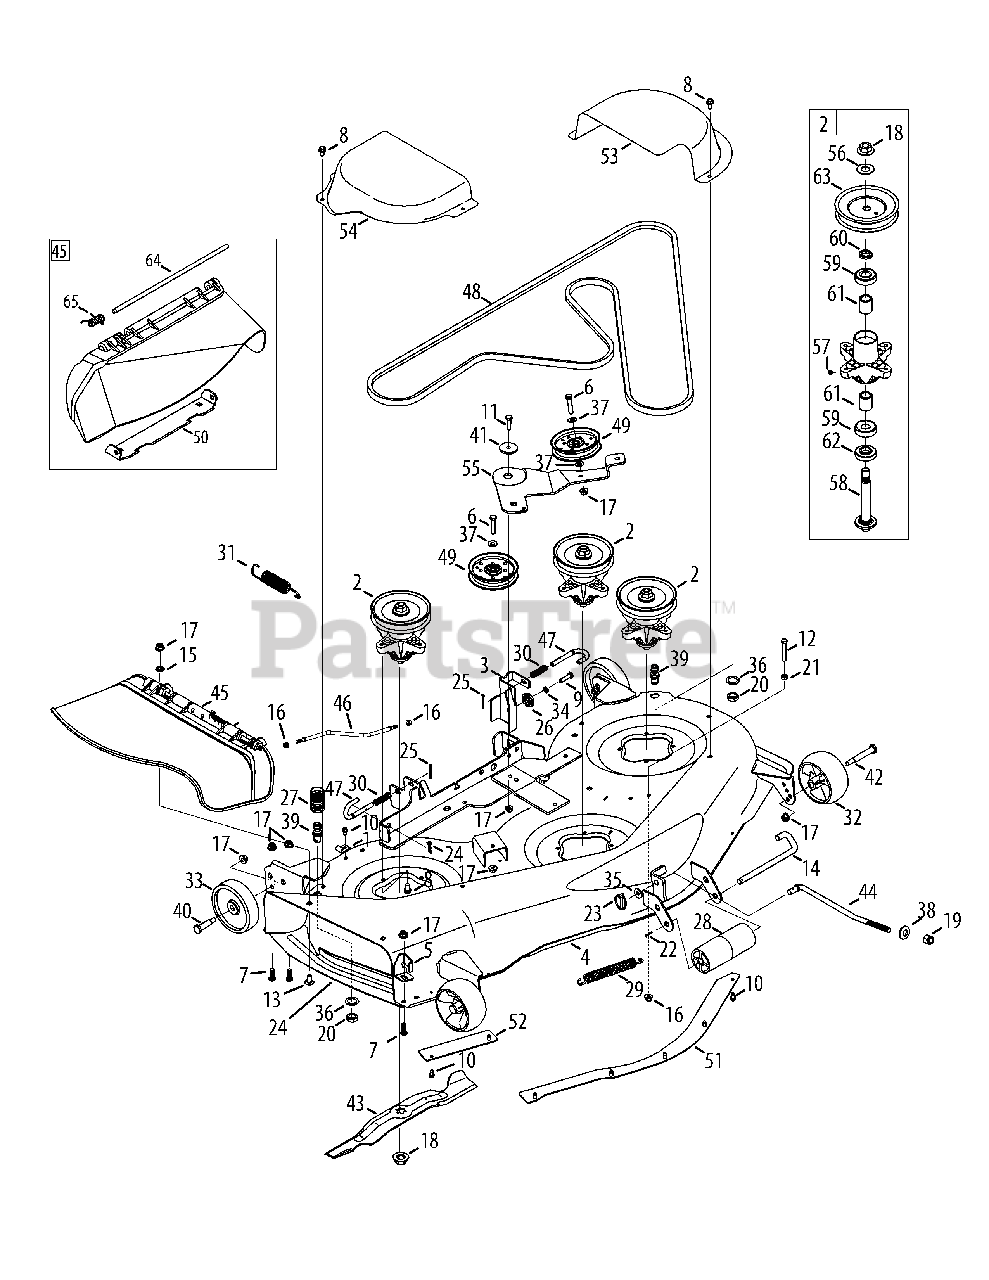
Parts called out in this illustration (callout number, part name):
1	Hook Retainer Bracket
2	Pulley Spindle Assembly, 5.39
3	Deck Hanger Bracket Assembly
6	Hex Screw, 3/8-16x1.75
7	Hex Screw, 3/8-16x1.00
8	Taptite Screw, 5/16-18x.750
9	Hex Screw, 5/16-18x1.25
10	Taptite Screw, 1/4-20x0.500
11	Hex Screw, 3/8-16x1.25
12	Hex Screw, 5/16-18x2.0
13	Carriage Bolt, 3/8-16x0.75
14	Roller Pin, 1/2 DIA x 7.31 LG
15	Push Nut, 3/8
16	Flangelock Nut, 5/16-18
17	Flangelock Nut, 3/8-16
18	Flange Nut, 5/8-18
19	Flexlock Nut, 1/2-13
20	Hex Nut, M16-1.5 DIN 936
21	Hex Nut, 5/16-18:GR5
22	Cotter Pin, 3/32x1.0
23	Lynch Pin, .1875
24	Finger Guard
25	Cotter Pin, 1/8 x 1.25
26	Deck Adjustment Gear
27	Water Nozzle Adaptor
28	Front Roller
29	Extension Spring, .94 DIA. x 6.74 LG
30	Compression Spring, .535 OD x 1.751 LG
31	Extension Spring, 1.15 OD x 5.99 LG
32	Front Deck Wheel
33	Rear Deck Wheel
34	Lock Washer, 5/16
35	Flat Washer, .531 x 1.25 x .100
36	Lock Washer, 5/8
37	Flat Washer, .406 x .875 x .059
38	Bell Washer, .63 x 1.25 x .18
39	Water Nozzle
40	Shoulder Bolt, .496 x 1.525x3/8-16
41	Shoulder Spacer, .8840 x .190
42	Shoulder Bolt, .496 x 2.50x3/8-16
44	Front Deck Lift Rod
45	Chute Assembly
46	Deck Sway Rod
47	Deck Release Handle Rod
48	V Belt
49	Idler Pulley, 4.25"DIA
50	Chute Bracket
51	Center Skirt
52	RH Skirt
53	LH Belt Cover
54	RH Belt Cover
55	Idler Bracket
56	Flat Washer, .760 x 1.50 x .120
57	Lube Fitting
58	Spindle Shaft
59	Ball Bearing, .787ID x 1.85
60	Spacer, .790 ID x 1.25 OD x .175
61	Spacer, .80 x 1.10 x 1.322
62	Spacer, .79 x 1.82 x .55
63	Deck Pulley
64	Hinge Pin
65	Torsion Spring
